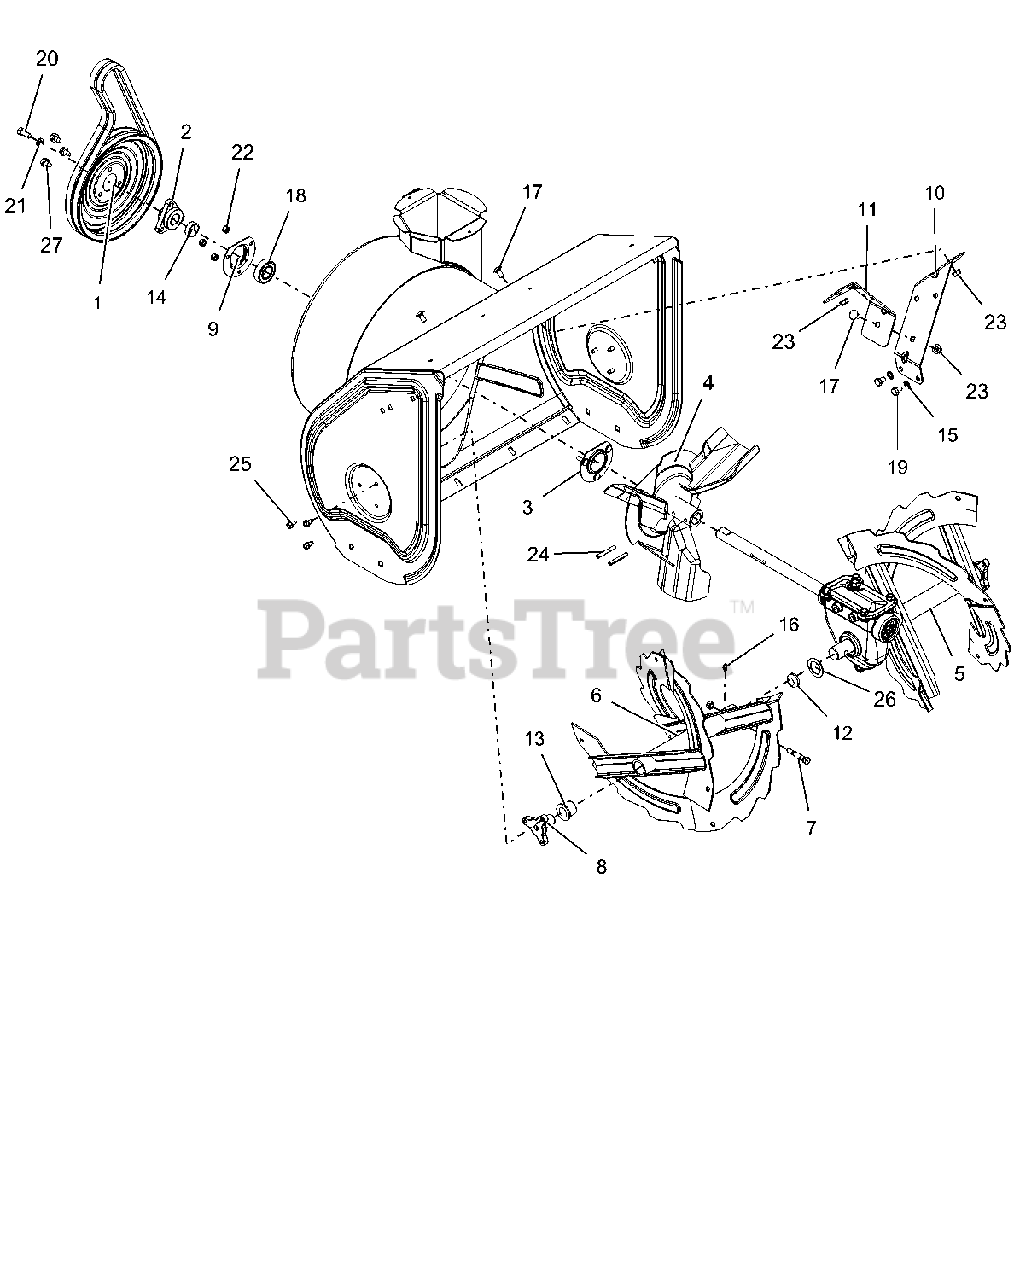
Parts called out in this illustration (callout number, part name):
1	PULLEY, SPIN FORM DUAL GROOVE
2	PULLEY HUB, D-BORE .87 DELUXE
3	BEARING FLANGE
4	IMPELLER, 3 BLADE-14"
5	RAKE, LH W/ZERK - 24"
6	RAKE, RH W/ZERK - 24"
7	SHEAR BOLT SERVICE ASSEMBLY
8	SUPPORT, RAKE BUSHING
9	BEARING FLANGE
10	BRACKET, GEARCASE SUPPORT - LH
11	BRACKET, GEARCASE SUPPORT - RH
12	PLUG, RAKE TUBE
13	BSHG-FLG, NY.778 ID X 1.018 OD
14	BSHG-SPCR .895IDX1.065ODX.353
15	@WSHR-LK-EXT.326X.599X.031YWZC
16	ZERK,FITTING .25X.125 DRIVE IN
17	BLT-RDHDSQSHNK.31-18X.62 YZ-LK
18	BRG-BALL .876 X 1.750 X .50
19	@BLT-HEX .31-18X.50 GR5 YWZC
20	BLT-HEX .31-24X.75 YWZC GR5
21	WSHR-LK .312X.097 HVY YWZC
22	@NUT-LK-CTR .25-20 YWZC
23	@NUT-LK-TOP-FLG .31-18 YWZC
24	PIN-ROLL .250X1.75
25	SCR-TAP .25-20X.50 HWH TR YWZ
26	WSHR-FL-STL 1.010X1.505X.062YZ
27	@SCR-TAP .31-18X.50 HWH TR YWZ
